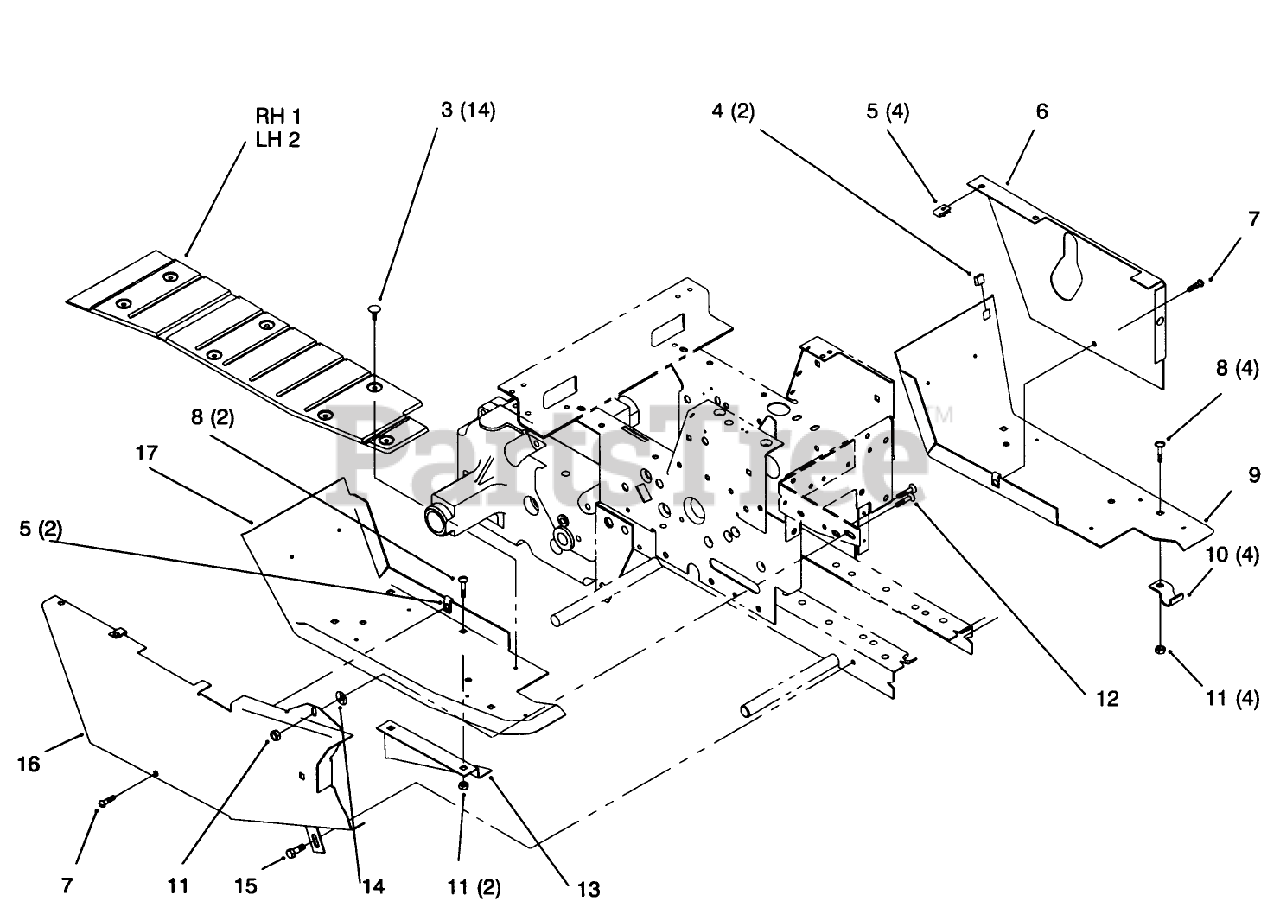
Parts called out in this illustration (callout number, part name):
1	PAD-FOOT RH
2	PAD-FOOT LH
3	FASTENER-PANEL
4	BUMPER
7	SCREW-PPH
8	BOLT-CARR
10	BRACKET
11	NUT-LOCK, NI
12	BOLT-CARR
